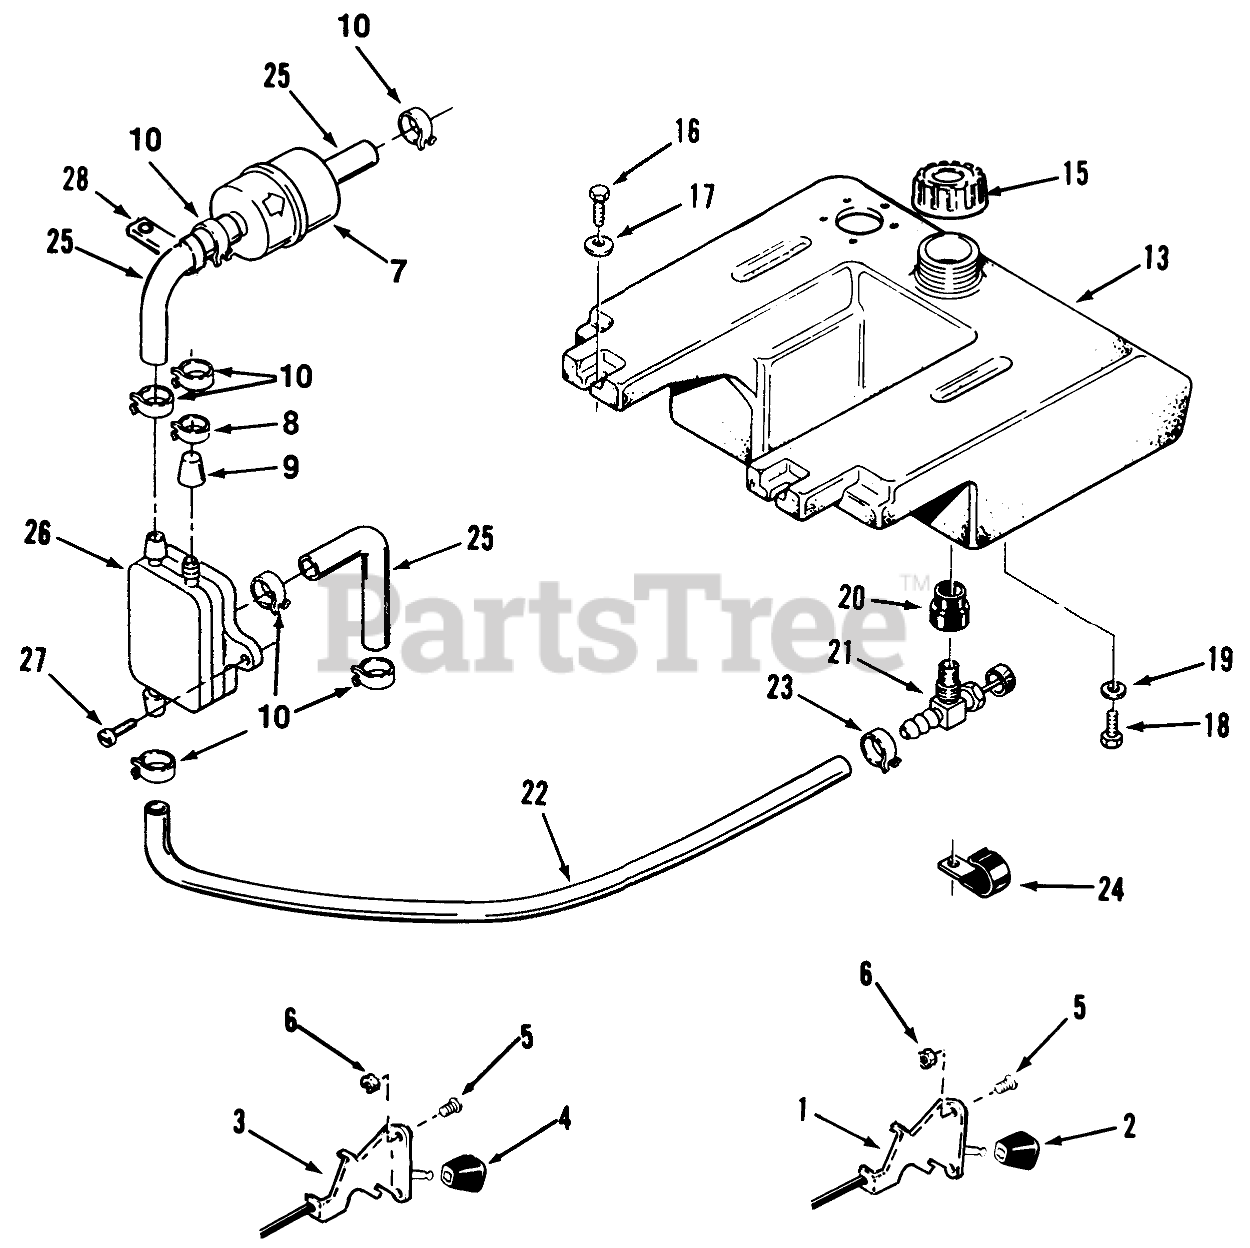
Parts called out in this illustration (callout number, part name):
1	CONTROL-THROTTLE
2	KNOB-CONTROL
3	CONTROL-CHOKE
4	NUT-HEX PALNUT
5	Screw
6	Nut
7	Filter-Fuel
8	CLAMP
9	CAP-FUEL OUTLET
10	Clamp
13	Fuel Tank (Includes items 20 & 21)
14	GAS CAP ASM
16	Bolt
17	Washer
18	Bolt
19	Lockwasher
20	BUSHING
21	VALVE-FUEL
22	Line-Fuel 53"
23	Clamp
24	Clamp
25	Hose
26	PUMP-FUEL
27	SCREW-TAPPING PAN HD
28	Clip
